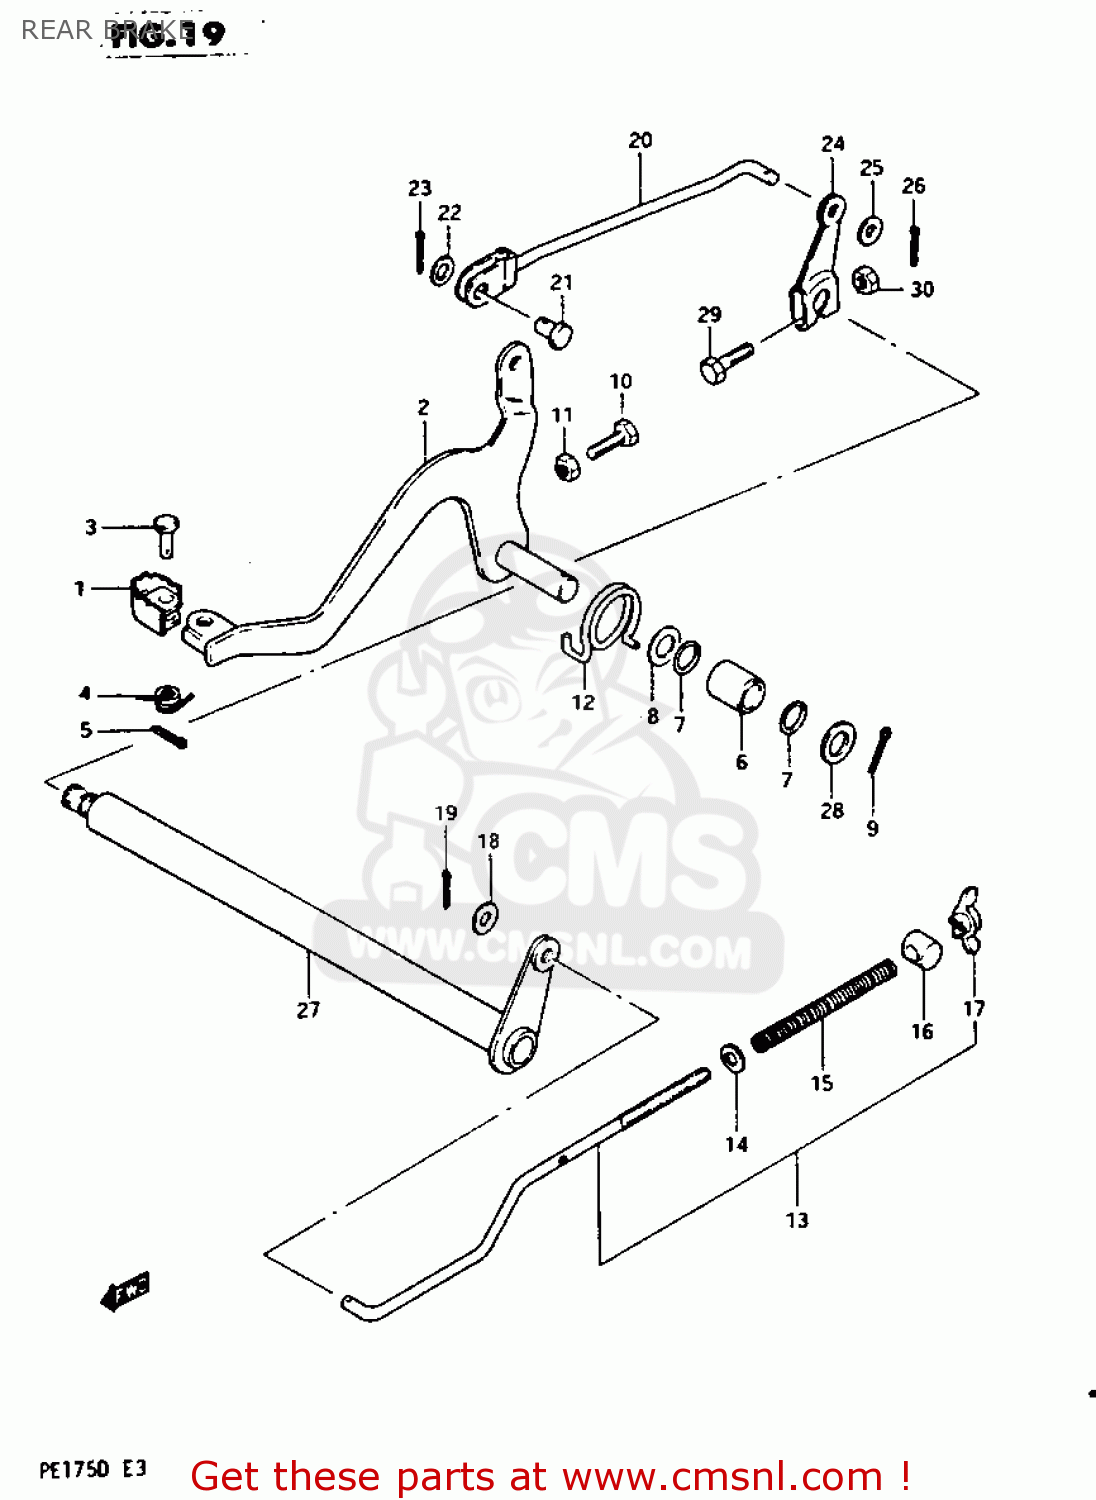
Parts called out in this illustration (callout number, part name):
1	PEDAL,BRAKE
2	ARM,BRAKE PEDAL
3	PIN
4	SPRING
7	O RING(D:2.2,ID:11.8)
8	WASHER
9	PIN 30X20
10	BOLT(6X23)
11	NUT
12	SPRING
13	ROD ASSEMBLY,REAR BRAKE,REAR
14	WASHER
15	SPRING
16	PIN
17	NUT
18	WASHER
19	PIN 20X20
20	ROD ASSEMBLY,REAR BRAKE FRONT
21	PIN(L:13.5)
22	WASHER
23	PIN 20X20
24	ARM,REAR BRAKE ROD,OUTER
25	WASHER
26	PIN 20X20
27	ARM,REAR BRAKE ROD
28	WASHER(12.1X30X2.3)
29	BOLT
30	NUT
